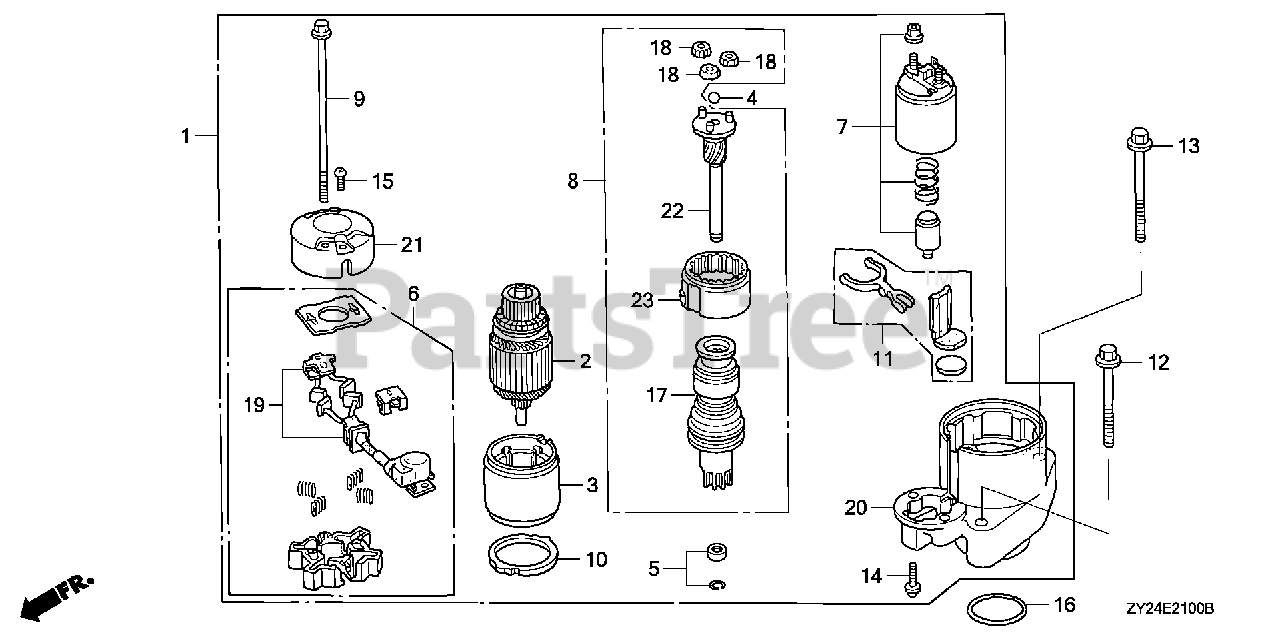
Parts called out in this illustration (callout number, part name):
1	STARTER MOTOR ASSY.
4	BALL, STEEL
5	STOPPER SET, SLEEVE
6	HOLDER, BRUSH
7	SWITCH ASSY., MAGNET
8	SHAFT ASSY., CLUTCH
9	BOLT A, THROUGH
12	BOLT, FLANGE (10X110)
12	BOLT, FLANGE (10X90)
13	BOLT, FLANGE (10X90)
13	BOLT, FLANGE (10X110)
14	SCREW, PAN (6X22) (SPECIAL)
15	SCREW, PAN (5X8)
16	O-RING (59.4X3.1)
17	CLUTCH, OVERRUNNING
18	GEAR ASSY., PLANETARY
20	BRACKET, FR.
21	BRACKET, RR.
22	SHAFT ASSY., GEAR
23	GEAR ASSY. (INNER)
